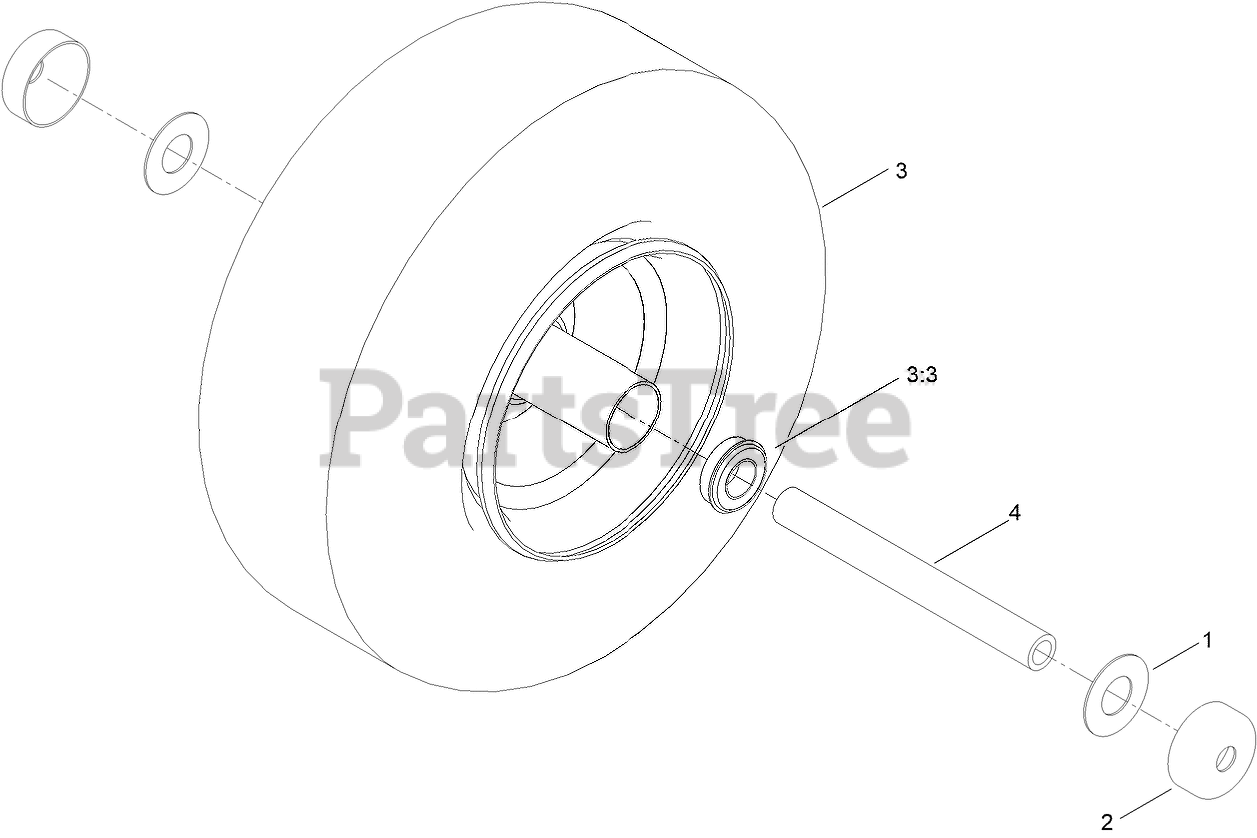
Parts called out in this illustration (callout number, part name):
1	WASHER
2	GUARD-SEAL
3	TIRE ASM
3:3	BEARING
4	SPANNER-WHEEL
